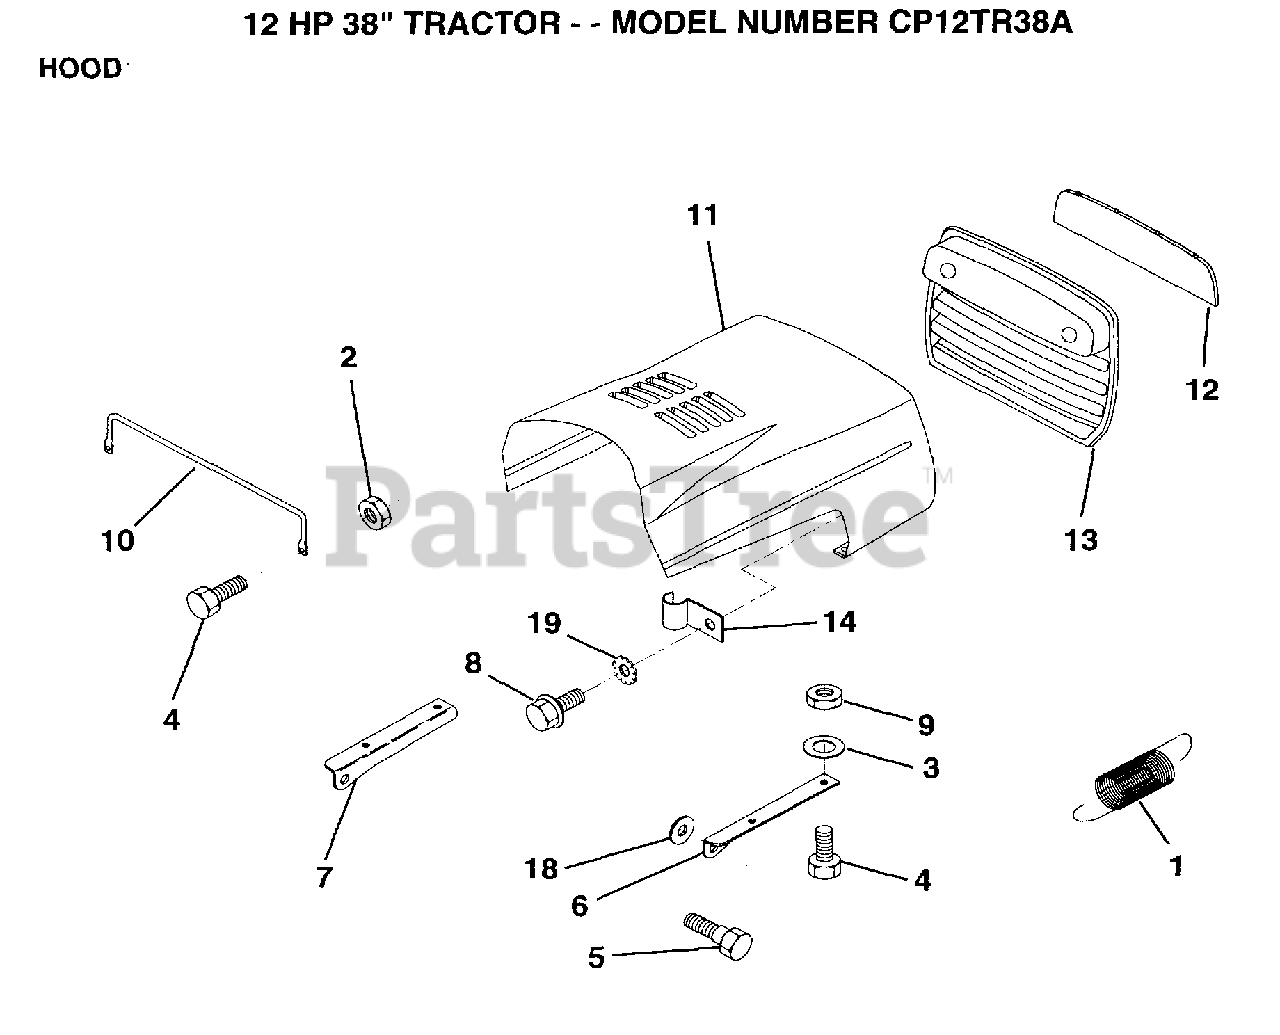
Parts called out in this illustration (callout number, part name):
1	EXT SPRING
2	NUT
3	WASHER
6	BRKT HOOD RH
7	BRKT HOOD LH
8	SCREW SLTD HXHD
9	NUT
10	"BRACE,HOOD"
12	LENS
13	GRILL
14	CLIP T
18	WASHER
19	LOCKWASHER GT
